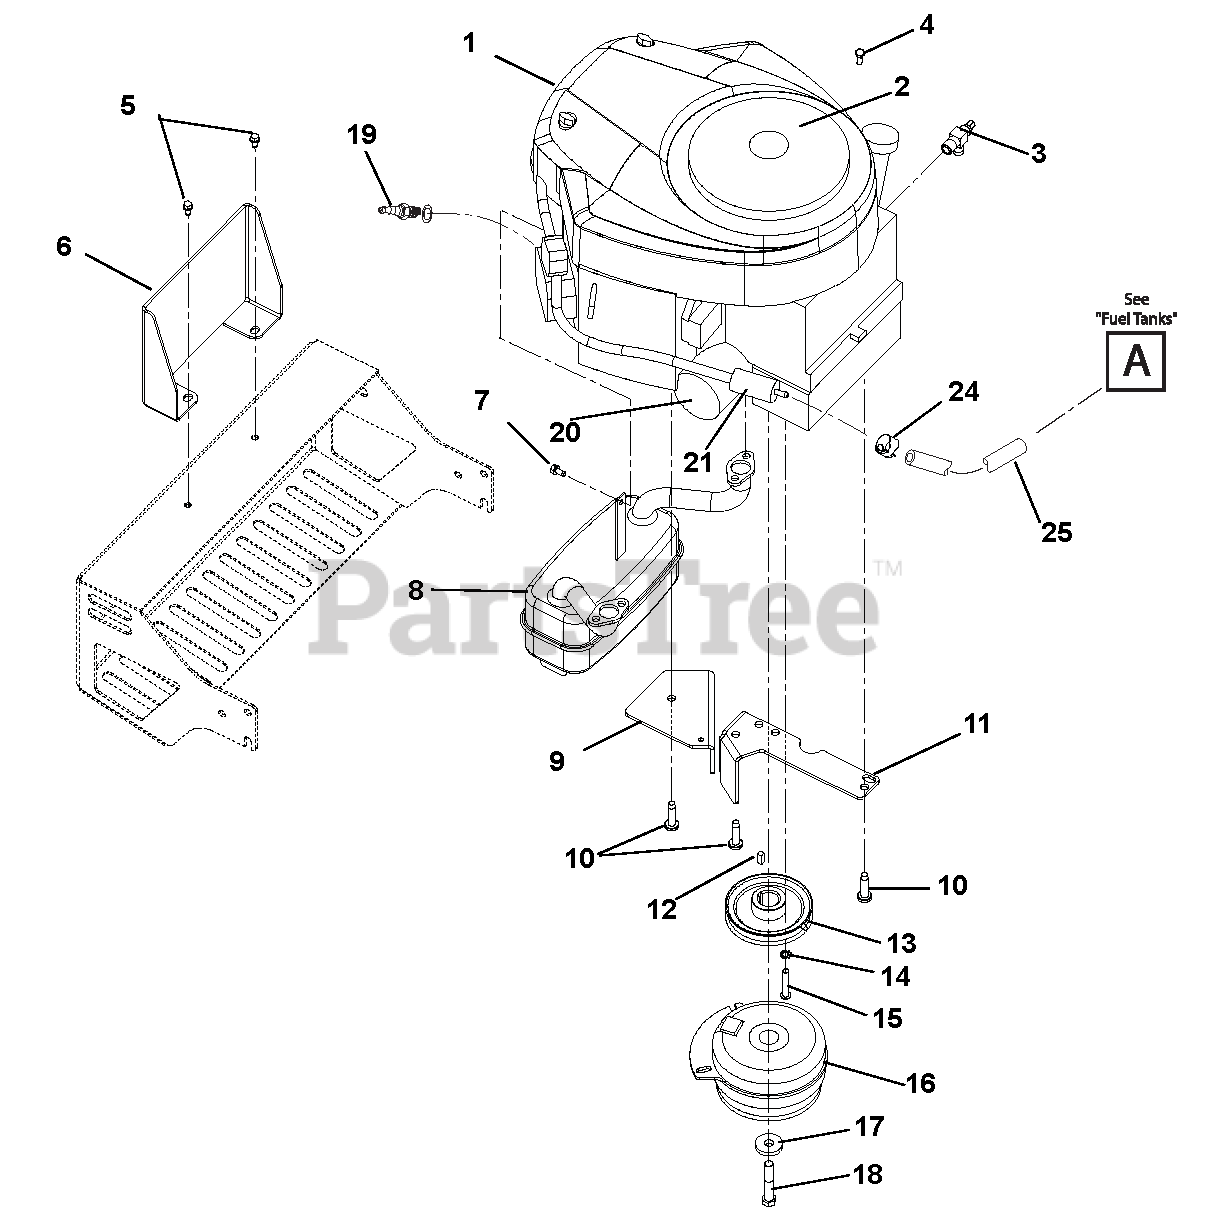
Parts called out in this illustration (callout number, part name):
1	ENGINE, 26HP BRIGGS ELS
2	GUARD, BRIGGS ENGINE
3	DRAIN, 1/2" OIL
4	SCREW, 8-16X.87 PHPAN 3 LOBE
5	@SCR-TAP .38-16X.75 HWH TR YWZ
6	BRIGGS CARBURETOR GUARD - BLK
7	@SCR-TAP .25-20X.50 HWH TR YWZ
8	MUFFLER ASSEMBLY
9	GUARD - CLUTCH WIRE - CZ
10	BLT, TAP .38-16X1.5 PH TRX YZ
11	WMT, CLUTCH STOP
12	KEY-SQ .25X.625X.25 SAE 8630
13	SHEAVE, 4.831 X 1.002 ENGINE
14	@WSHR-LK-EXT.391X.628X.036YWZC
15	BLT-BTNHD .31-18 X 1.75 YWZC
16	CLUTCH, ELECTRIC
17	WSHR-FL-STL.463X1.375X.25 YWZC
18	BLT-HEX .44-20X2.50 G5 YZ EP80
19	PLUG, SPARK
20	FILTER, OIL
21	FILTER, FUEL
22	FILTER, AIR
23	FILTER, AIR PRE-
24	CLAMP, FUEL LINE
25	HOSE, .25 LOW-PERM BULK GAS
